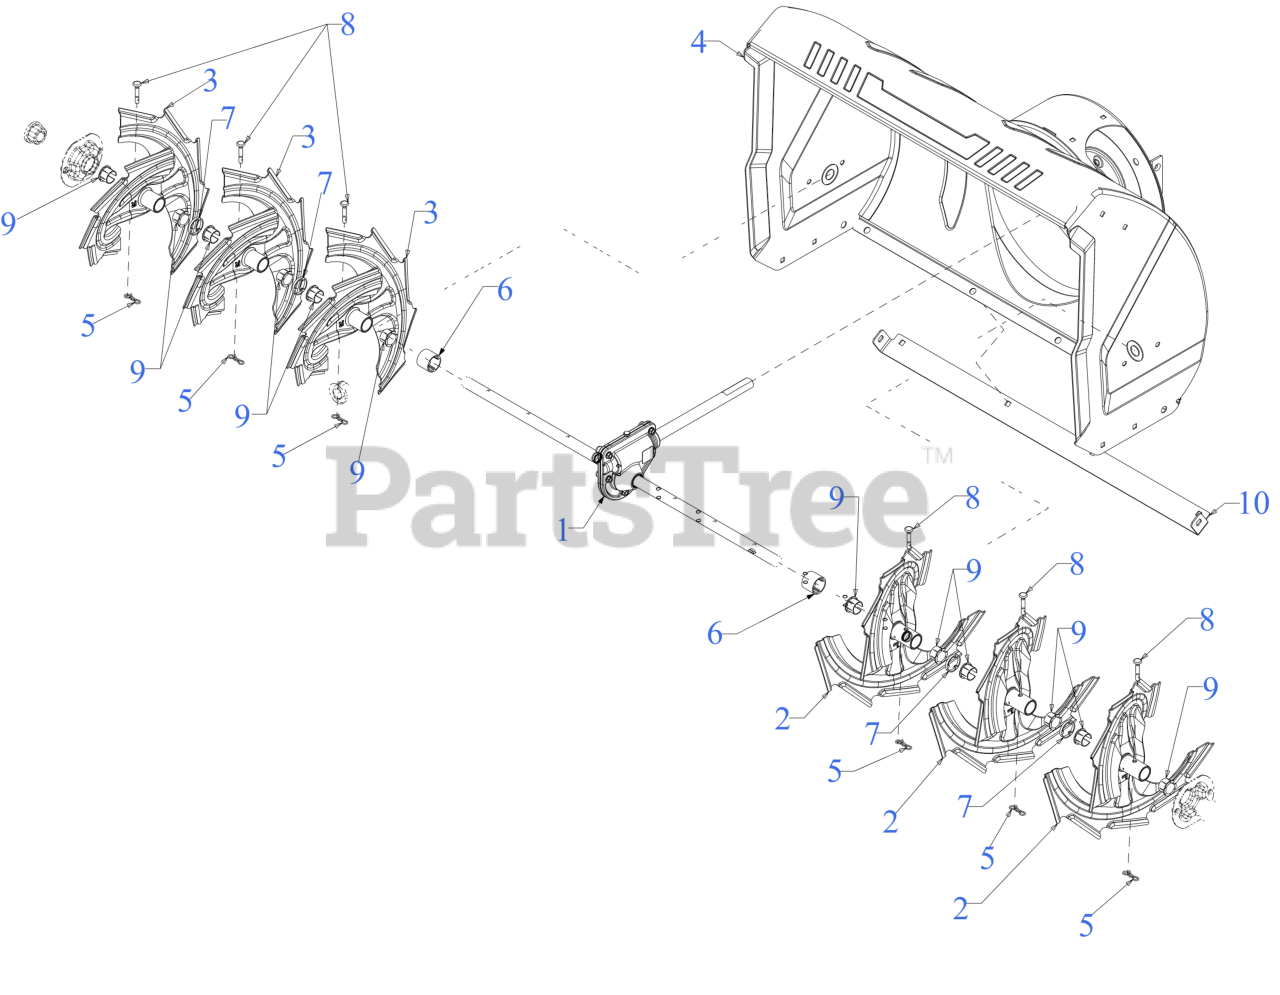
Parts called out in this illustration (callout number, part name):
1	AUGER GEARBOX ASSEMBLY 30"
2	10T AUGER SPIRAL (LH)
3	10T AUGER SPIRAL (RH)
4	30" AUGER HOUSING
5	BOW TIE COTTER PIN 1/4-5/16
6	SPACER 1.25OD x .75ID X1.00 LG
7	SPCR 1.25 OD x 75IDX2.00LG
8	SHEAR PIN .25 x 1.50 GR2
9	FLANGE BUSHING
10	30" SHAVE PLATE
